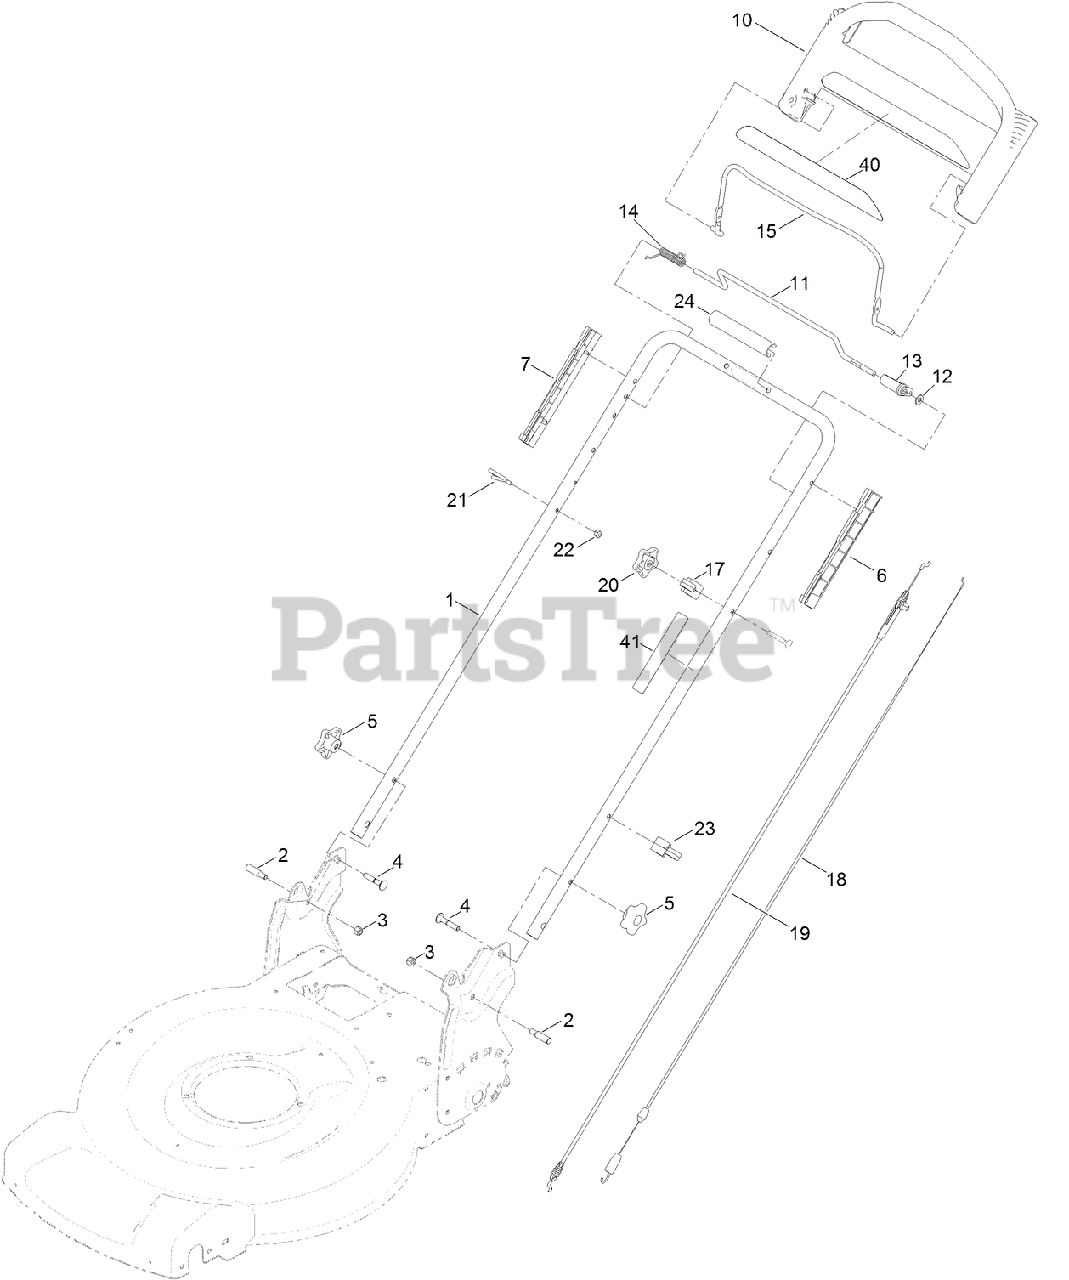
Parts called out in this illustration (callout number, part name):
2	BOLT-SHOULDER
3	NUT-LOCK, NI
4	SCREW-CARR
5	KNOB-HANDLE
6	GUIDE-LH
7	GUIDE-RH
10	HANDLE-CONTROL
12	WASHER-PLAIN
13	LEVER-TRACTION
15	BAIL-BRAKE
17	ANCHOR-CABLE
18	CABLE-TRACTION
19	CABLE-BRAKE
20	KNOB-HANDLE, LOCKING
21	GUIDE-ROPE
22	NUT-LOCK, NI
23	GUIDE-CABLE
24	HANDLE-COVER
40	DECAL-HANDLE
41	DECAL-TRACTION, ADJUST
